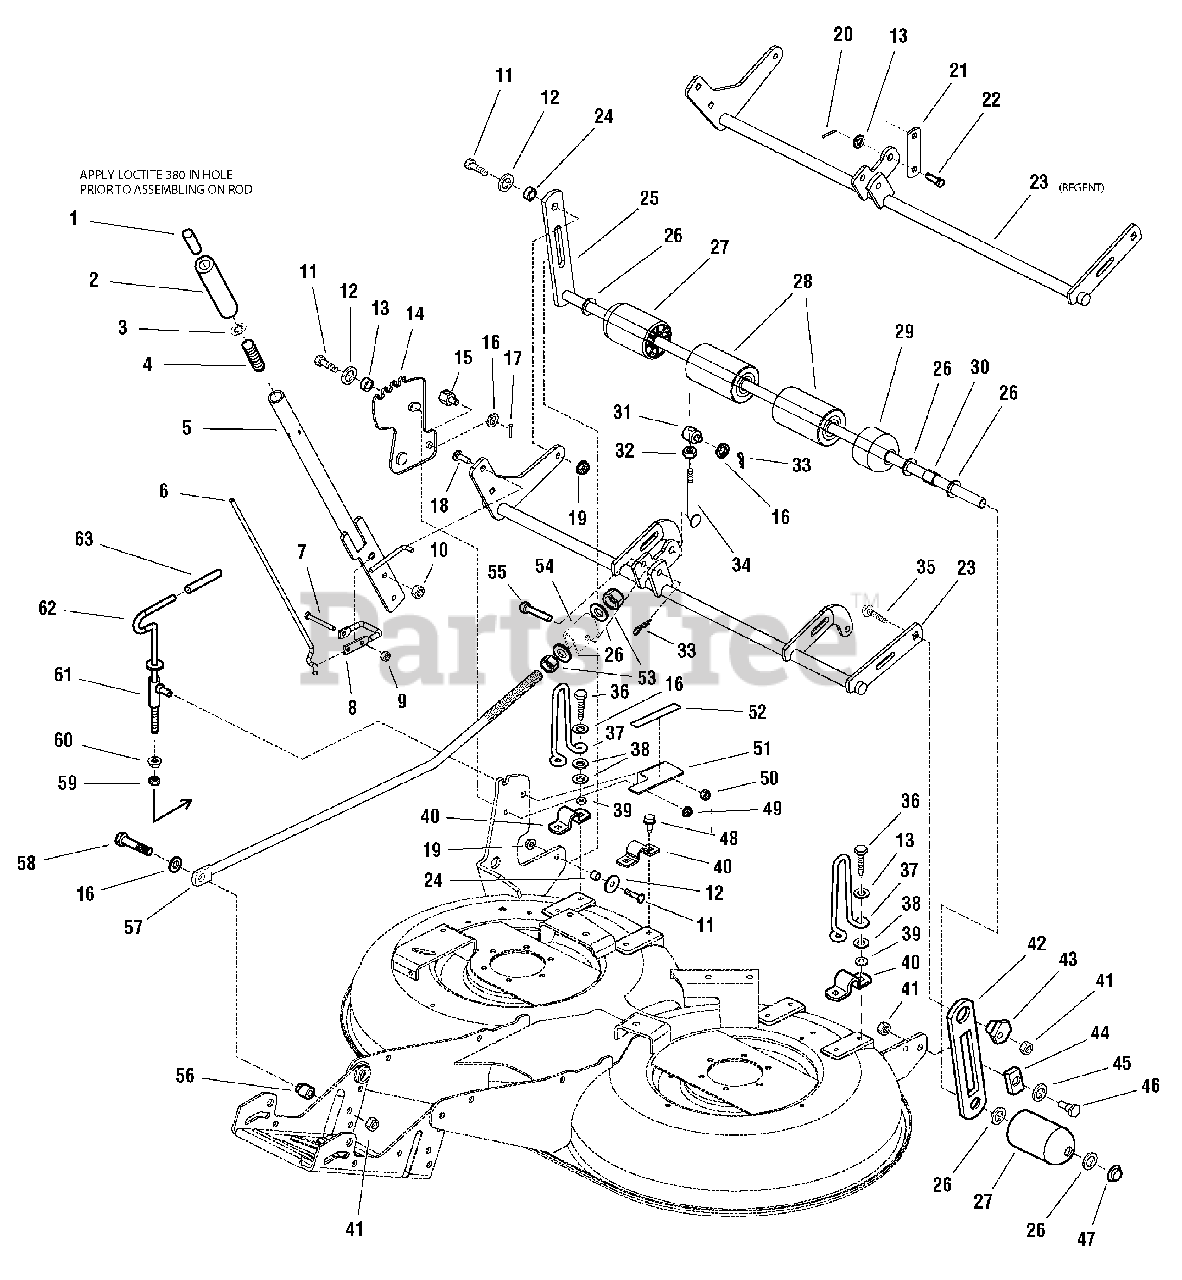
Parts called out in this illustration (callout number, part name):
1	BUTTON
2	GRIP, Lift Lever
3	NUT, Push 1/4 Thread
4	SPRING, Compression
5	HANDLE ASSEMBLY, Lift
6	ROD, Latch
7	CAPSCREW, Hex Head, 1/4-20 x 2-1/4
8	LATCH
9	NUT, Hex Lock, ESNA, 1/4-20
10	NUT, 5/16-18, Hex Flange Whiz Lock Small
11	CAPSCREW, Hex Head, 5/16-18 x 1-1/4
12	WASHER, Plain, 21/64 x 1-1/4
13	SPACER
14	BRACKET, Adjusting
15	PIVOT
16	WASHER, 3/8
17	PIN, Cotter 3/32 x 3/4
18	CARRIAGE BOLT, 5/16-18 x 1
19	NUT, Hex Flange Collar Lock, 5/16-18
20	PIN, Cotter
21	LINK, Lift Mower
22	PIN, Clevis
23	SHAFT ASSEMBLY, Rocker Mulch
24	SPACER
25	SHAFT & BAR ASSEMBLY
26	WASHER, 5/8
27	ROLLER, Rounded End
28	ROLLER
29	ROLLER, End
30	SPACER
31	TRUNNION
32	NUT, Jam, 5/16-18
33	CLIP, Spring
34	ROD, Height Adjustment
35	CARRIAGE BOLT, 3/8-16 x 1-1/2
36	CAPSCREW, Taptite, 5/16-18 x 1-1/4
37	UPSTOP
38	WASHER, Plain, 5/16
39	NUT, Push
40	STRAP
41	NUT, Hex Toplock Spiral Flange, 3/8-16
42	BAR, Roller
43	NUT, Adjuster
44	SLIDE
45	WASHER, Plain
46	SHOULDER BOLT
47	PUSH NUT, 5/8
48	CAPSCREW, Hex Head, Taptite, 5/16-18 x 3/4
49	NUT, Hex, Flange Lock, 5/16-18
50	NUT, Hex, Flange, Locking, 3/8-16
51	BRACKET, Height of Cut
52	DECAL, Height
53	NUT, Hex, Full, 5/8
54	TRUNNION, Rod
55	Pin
56	SPACER, 3/8 x 3/4 x 15/16
57	ROD, Adjusting
58	CAPSCREW, Hex Head, 3/8-16 x 1 3/4
59	NUT, Jam, Hex, 3/8-16
60	NUT, Hex Flange, 3/8-16
61	SOCKET ASSEMBLY
62	ROD & WASHER ASSEMBLY, Adjust Handle
63	GRIP
